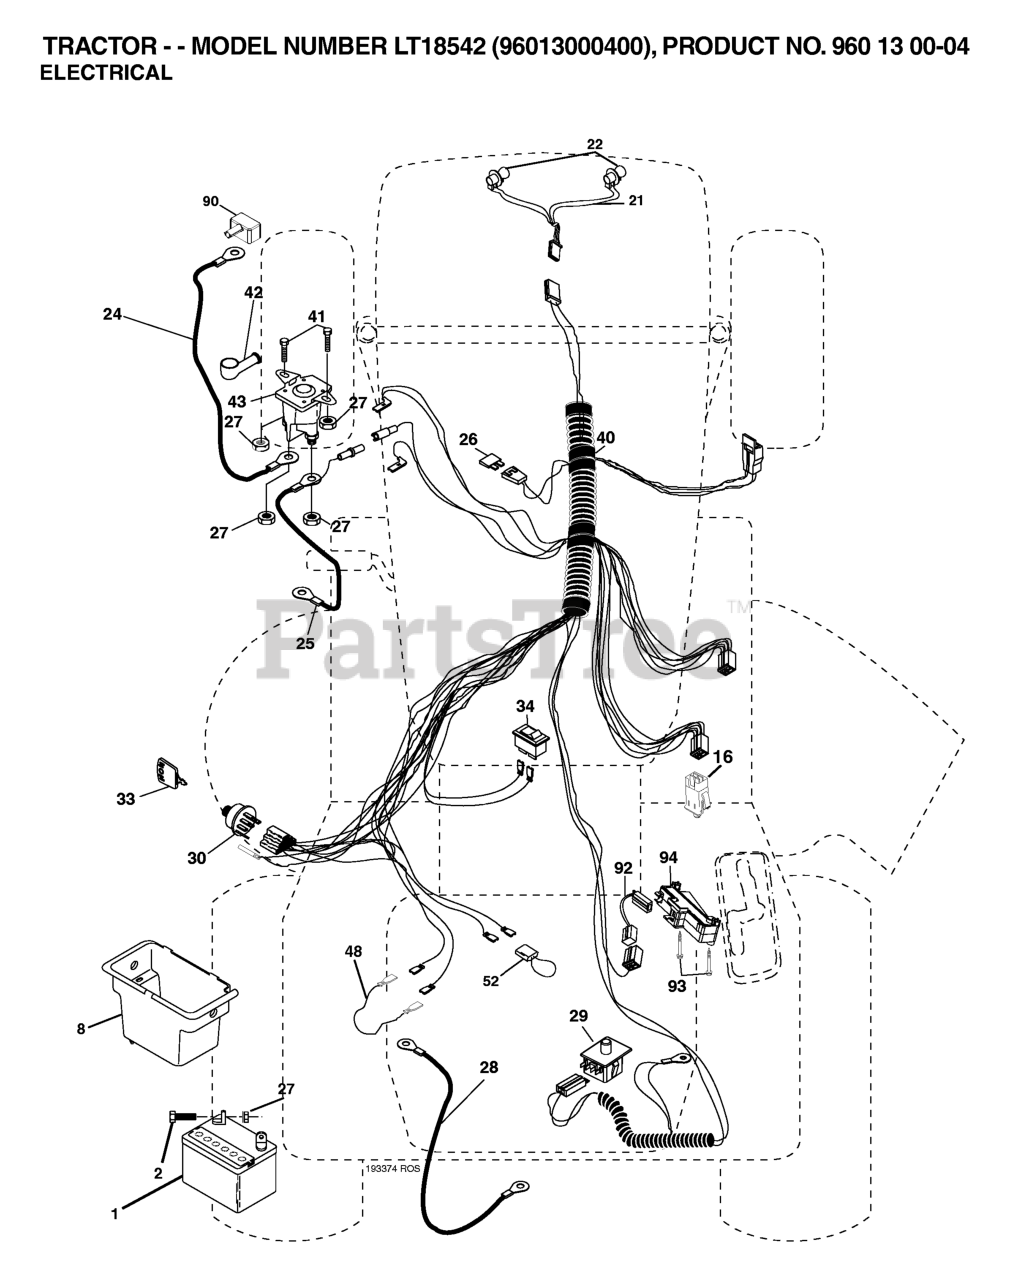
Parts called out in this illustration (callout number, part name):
1	BATTERY 12V .35 AMP
2	BOLT.HEX.1/4.X.3/4.DICHROMATE
8	BOX.BATTERY.FENDER
16	SWITCH INTERLOOK PUSH-IN
21	HARNESS.W/LIGHT SOCKET
24	BATTERY CABLE GT
25	CABLE BATTERY
26	FUSE 20AMP
27	NUT
28	CABLE T
29	SWITCH.SEAT.DP W/RAMPS
30	SWITCH.IGN.DELTA.W.LGH.ROS
33	KEY MLD GEN DELTA
40	Harness Ign
41	BOLT
42	TERMINAL COVER
43	SOLENOID
48	ADAPTER.AMMETER
52	WIRE PROTECTION LOOP
90	COVER TERMINAL
92	HARNESS.PIGTAIL.REVERSE.SWITCH
93	SCREW.PLASTITE
94	MODULE.REVERSE.ROS
